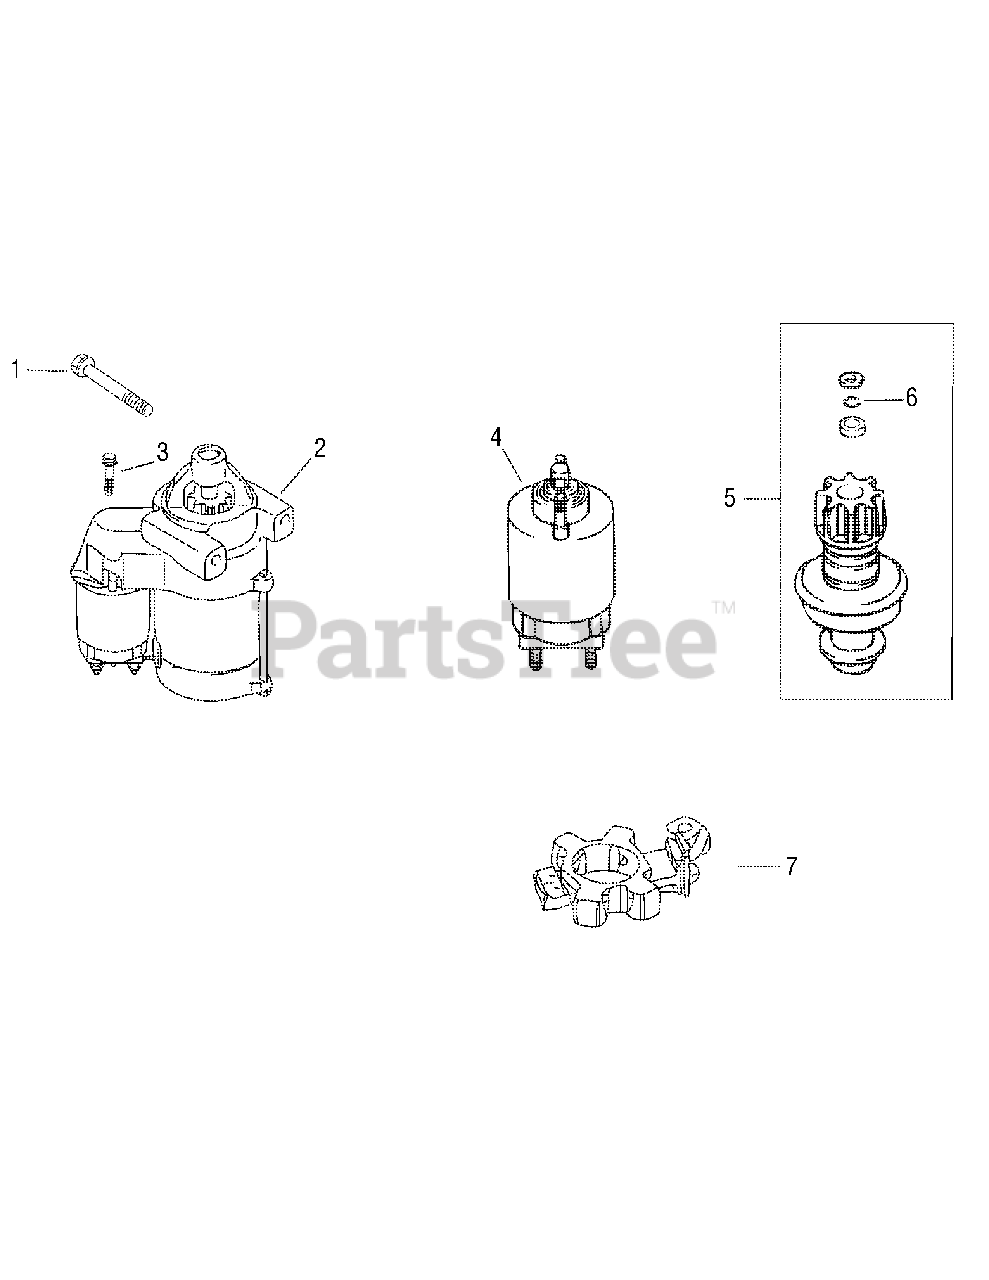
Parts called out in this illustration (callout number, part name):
1	Screw, hex. flange M8 x 1.25 x 80
2	Starter, solenoid shift (Includes 3-7)
3	Screw, external torx hd.
4	Kit, solenoid (Includes 3)
5	Kit, starter pinion (Includes 6)
